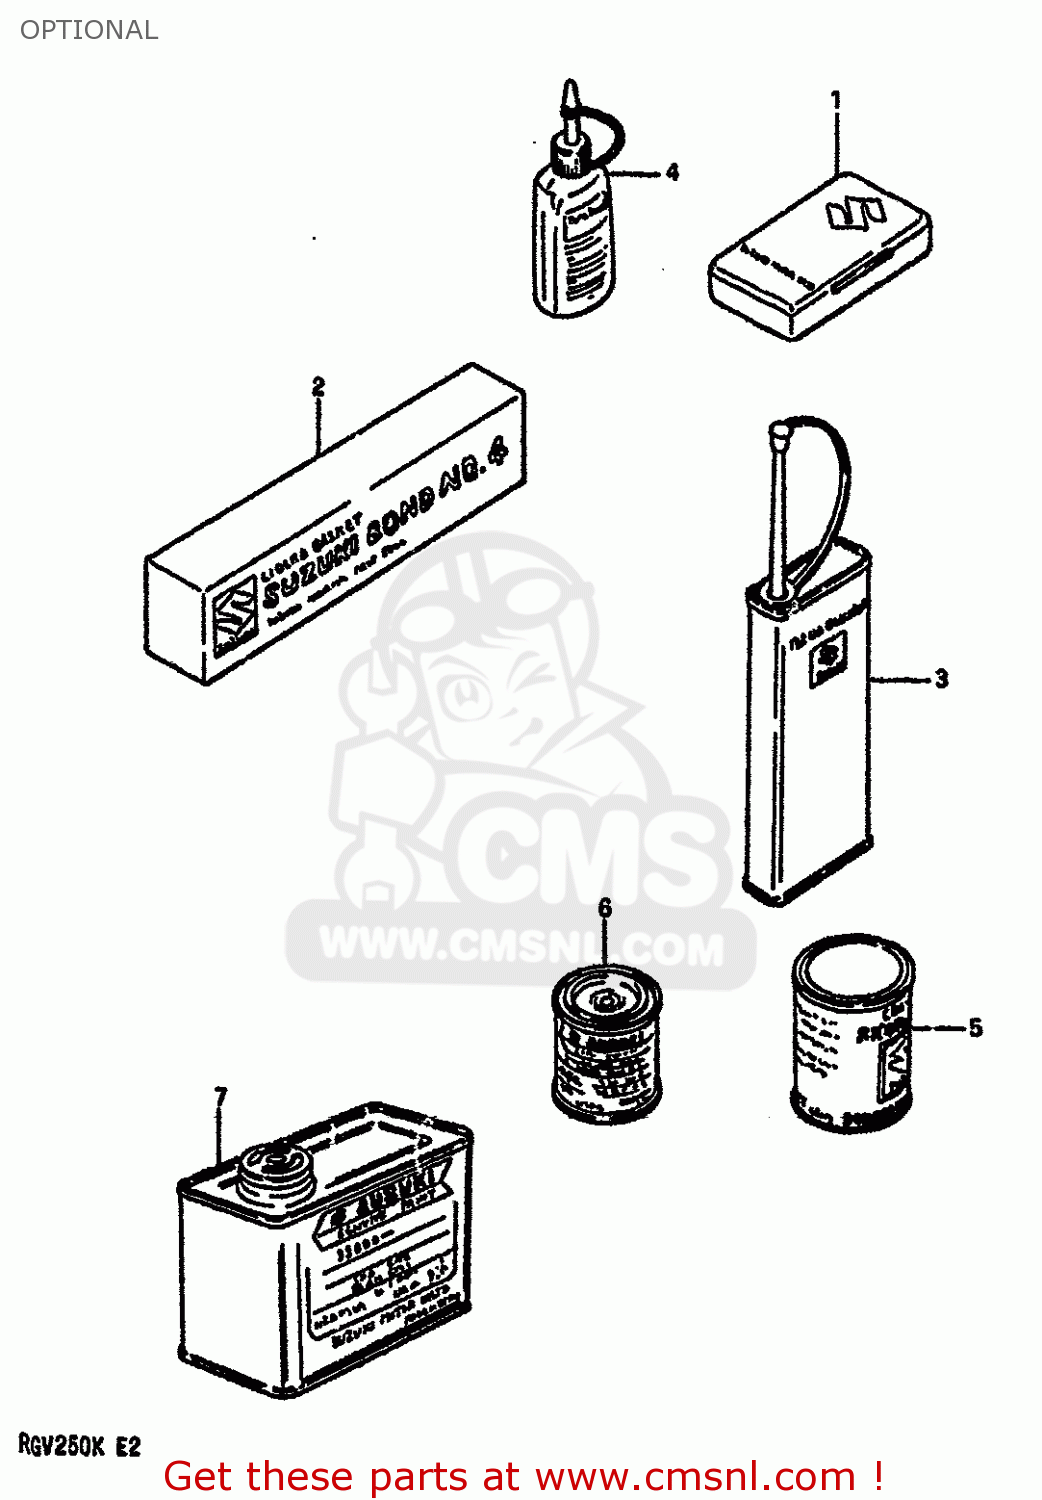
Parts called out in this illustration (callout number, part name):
1	TUBE REPARING TOOL
2	BOND 1104
3	THREAD LOCK NO.1401 CLEAR 200G
4	THREAD LOCK NO
5	GREASE(C)EP2 LITHIUM 150G
6	PAINT (SPECIAL WHITE)
7	PAINT (SPECIAL WHITE)
